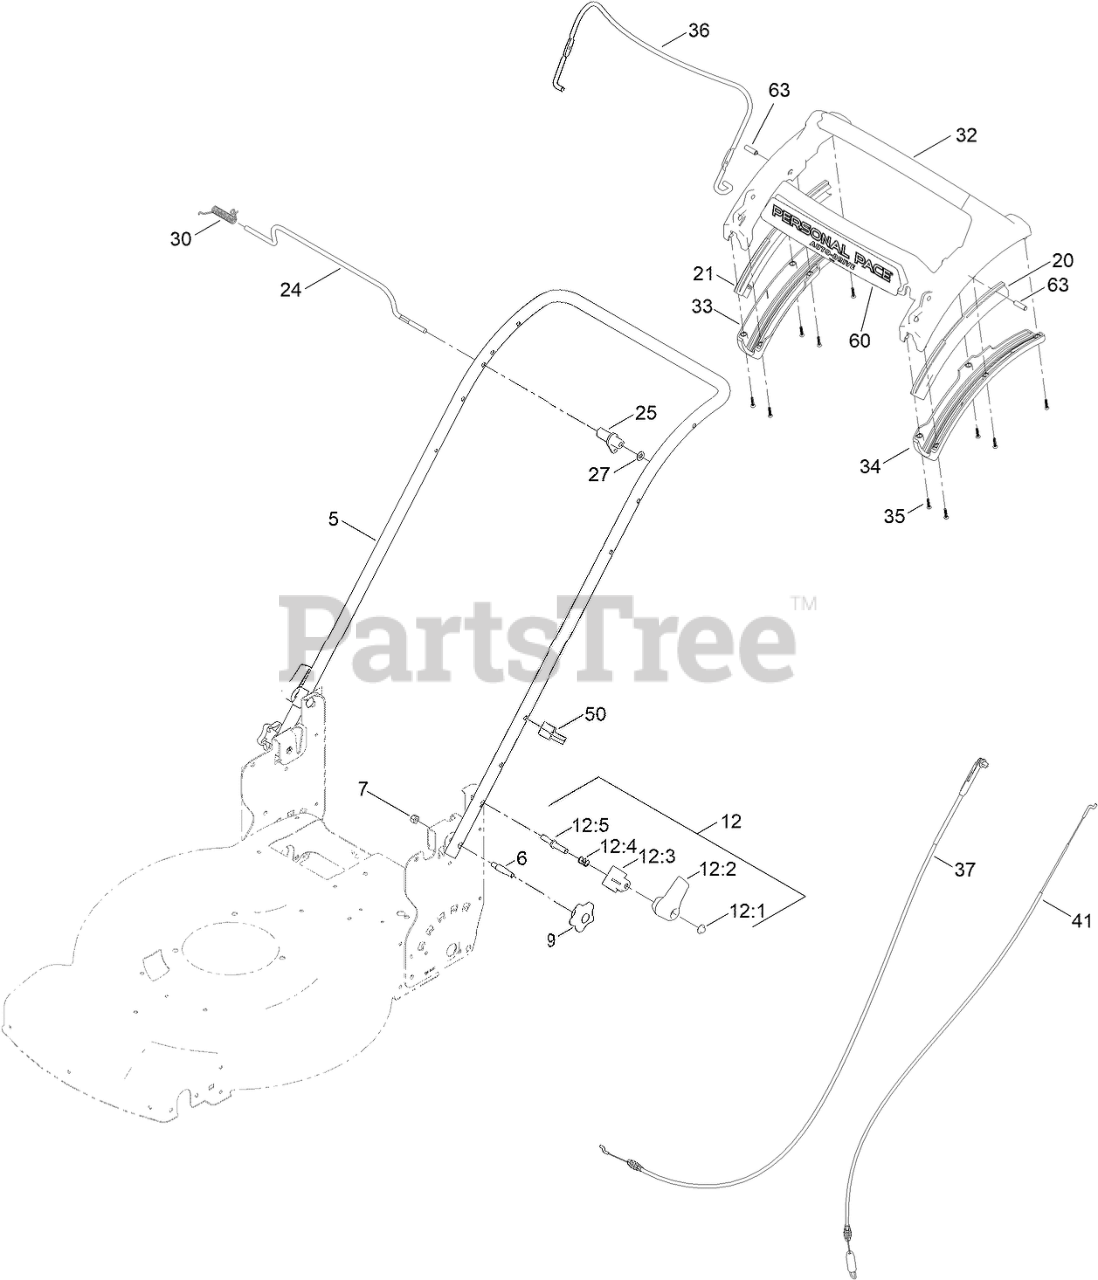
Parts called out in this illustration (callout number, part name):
5	HANDLE-CURVED
6	BOLT-SHOULDER, HANDLE
7	NUT-LOCK, NI
9	KNOB-HANDLE
12	QUICK RELEASE ASM
12:1	NUT-PUSH
12:2	LEVER-RELEASE
12:3	ANCHOR-SPRING
12:4	SPRING-COMPRESSION
12:5	ROD-RELEASE
20	GUIDE-CURVED, LH (RWD)
21	GUIDE-CURVED, RH (RWD)
24	ROD-CONTROL, TRACTION
25	LEVER-TRACTION, RWD
27	WASHER-PLAIN
30	SPRING-TORSION
32	HANDLE-PERSONAL PACE, CURVED
33	BOTTOM-HANDLE, RH
34	BOTTOM-HANDLE, LH
35	SCREW-PPH
36	BAIL-BRAKE
37	CABLE-BRAKE, PP BS
41	CABLE-TRACTION, RWD (PP)
50	GUIDE-CABLE
60	DECAL-60V, PERSONAL PACE
63	PIN-HANDLE, PP
